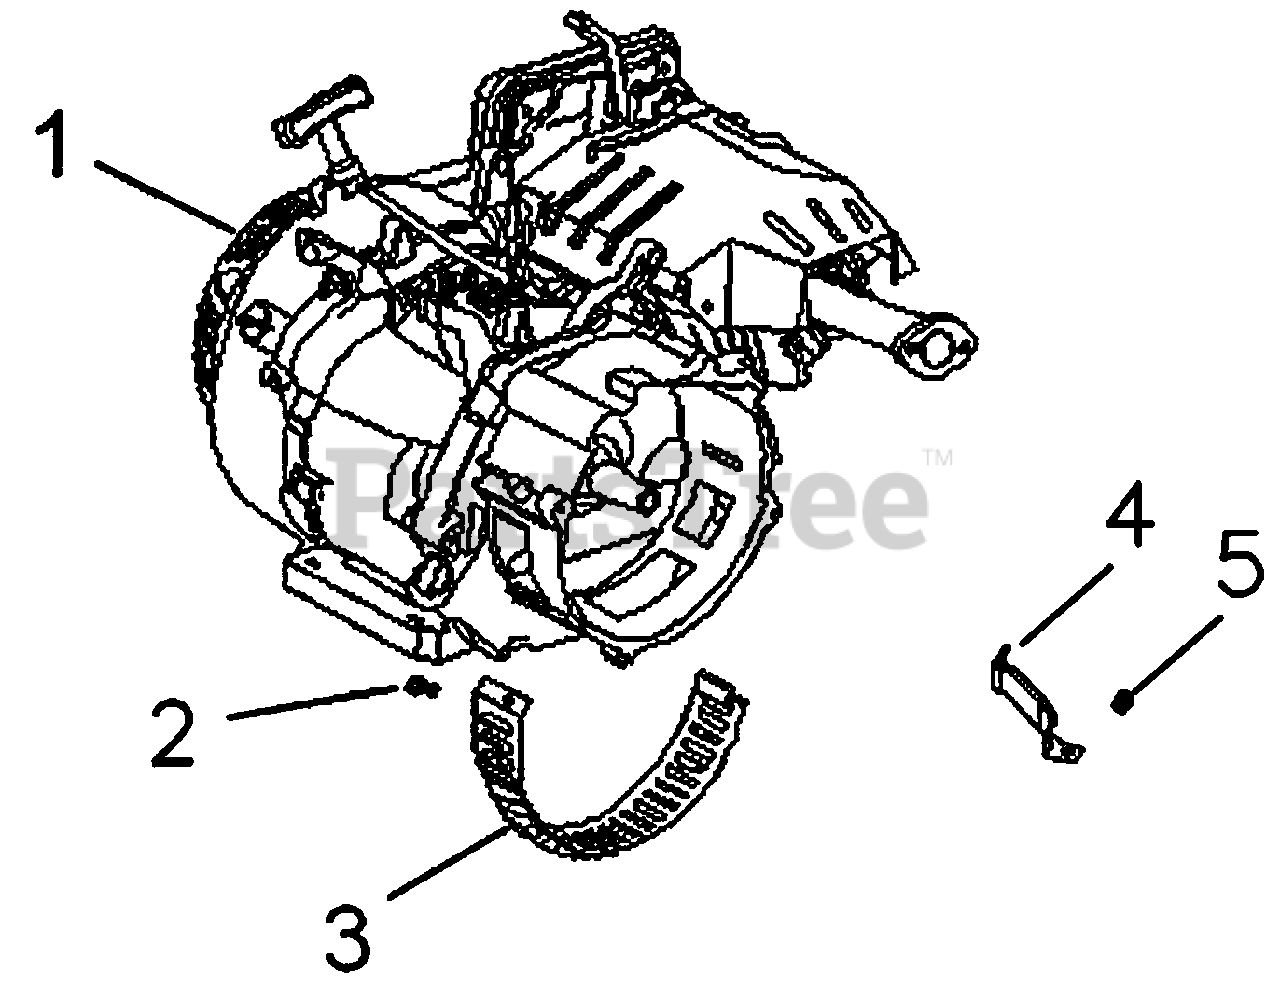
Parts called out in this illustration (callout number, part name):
1	ENGINE G390FDA
2	BOLT, FLANGE M5x10
3	COVER, DUST
4	BRACKET,AIR CLEANER
5	NUT, FLANGE M6
